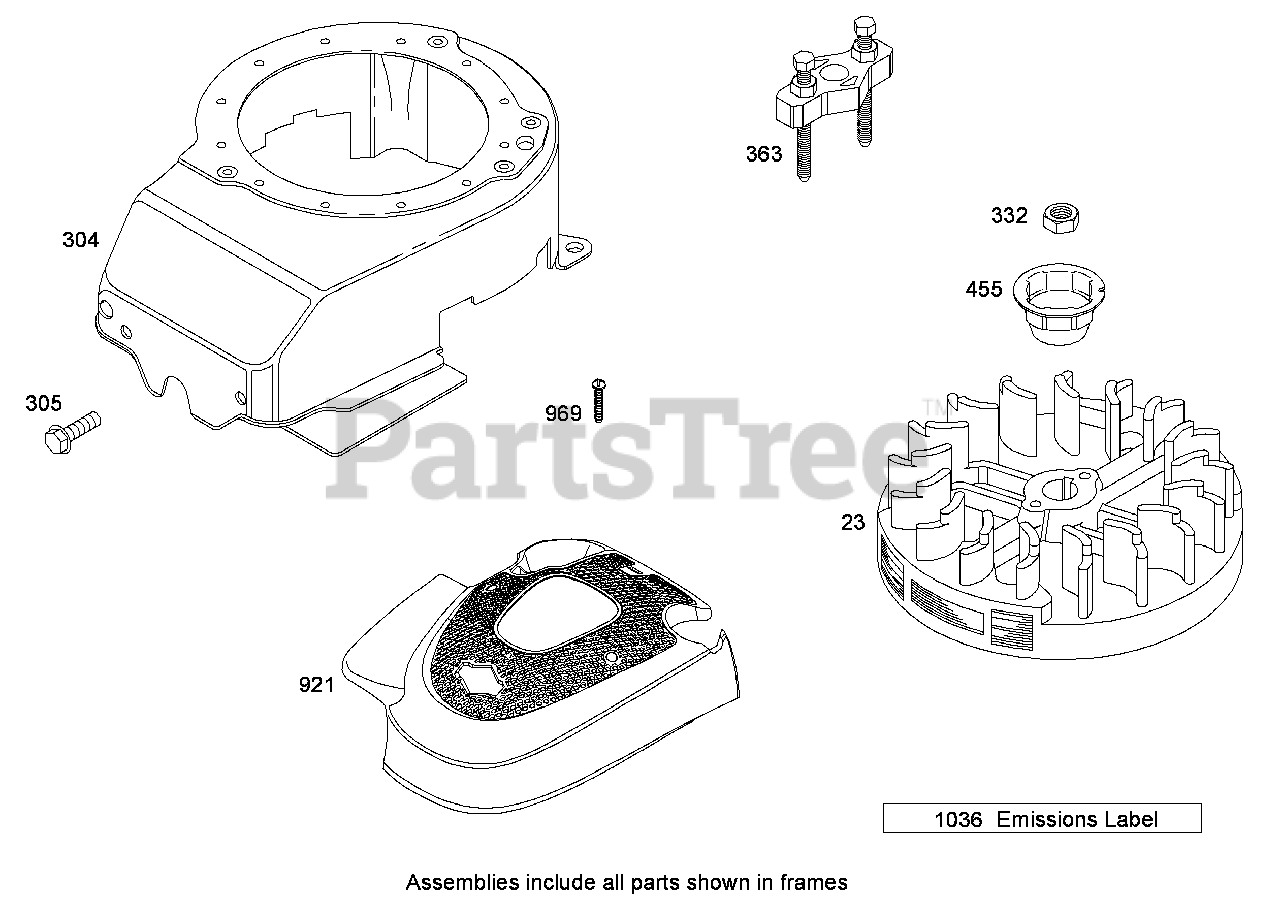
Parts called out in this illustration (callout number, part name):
23	Flywheel
304	Housing-Blower
305	Screw (Blower Housing)
332	Nut (Flywheel)
363	Puller-Flywheel
455	Cup-Flywheel
921	Cover-Housing, Blower
969	Screw (Blower Housing Cover)
1036	Label-Emissions
